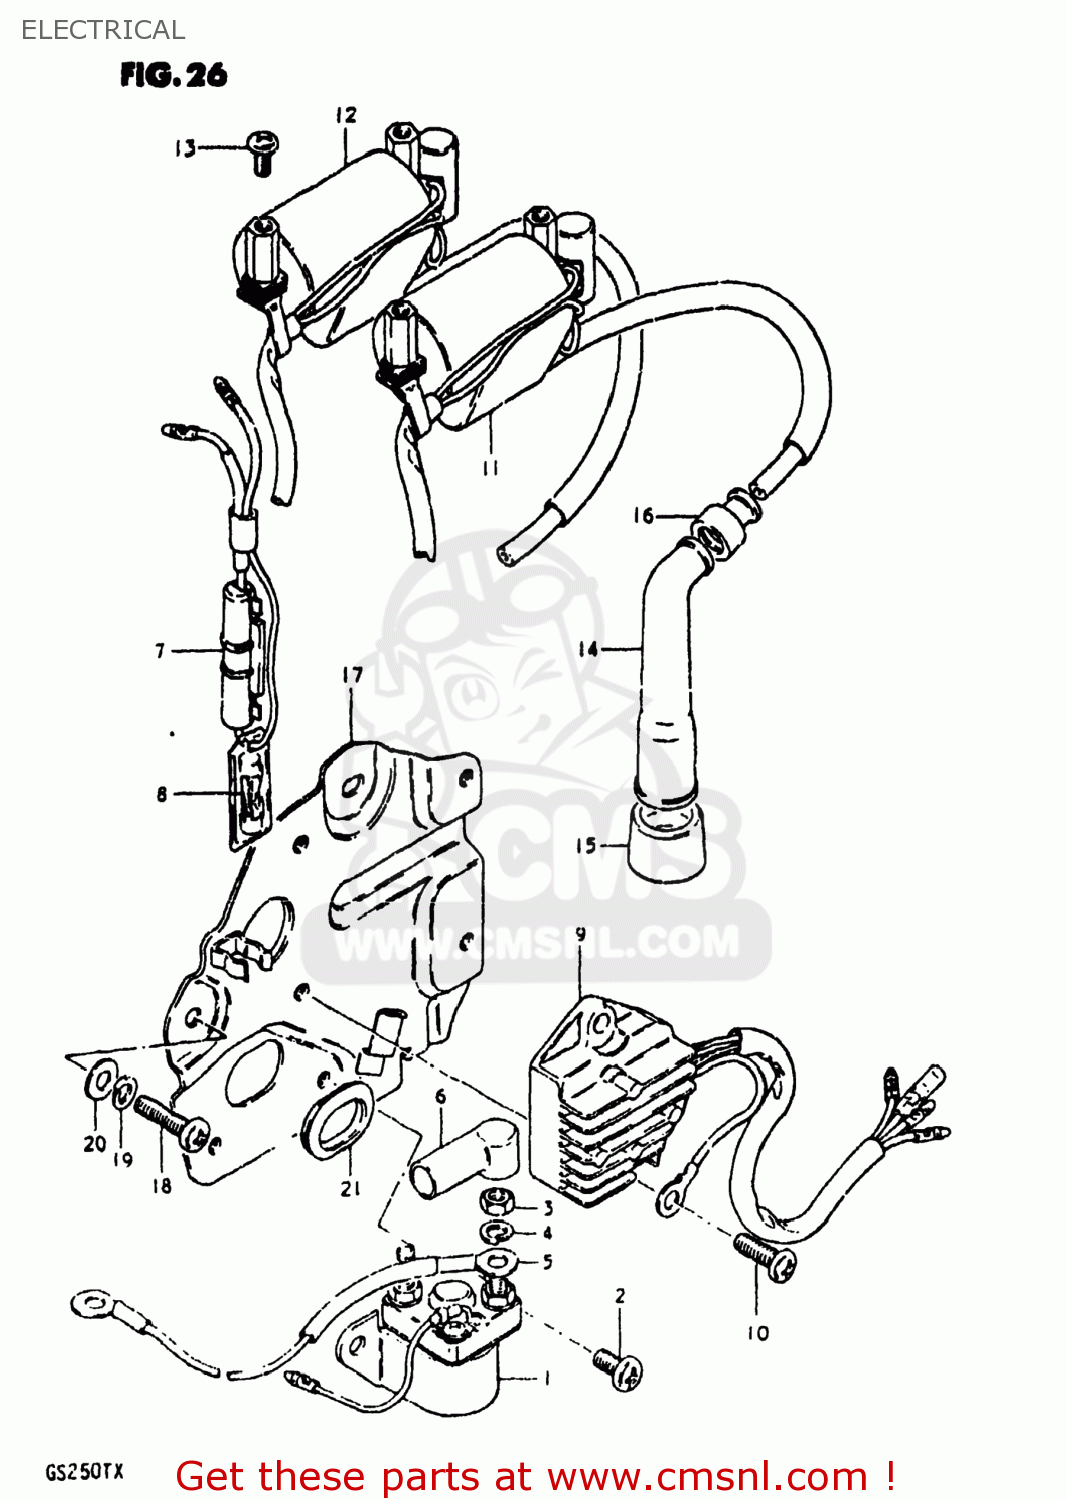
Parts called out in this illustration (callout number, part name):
1	RELAY ASSY,STARTING MOTOR
2	SCREW
3	NUT 6MM
4	WASHER,LOCK
5	CORD,BATTERY MINUS
6	CAP,STARTER RELAY
7	BOX ASSEMBLY,FUSE
8	FUSE(15A)
9	RECTIFIER ASSEMBLY
10	SCREW
11	COIL ASSEMBLY,IGNITION
12	COIL ASSEMBLY,IGNITION
13	SCREW
14	CAP,SPARK PLUG
15	SEAL,SPARK PLUG
16	SEAL,SPARK PLU
17	PLATE,ELECTRIC PARTS H
18	SCREW
19	LOCK WASHER
20	WASHER
21	GROMMET
